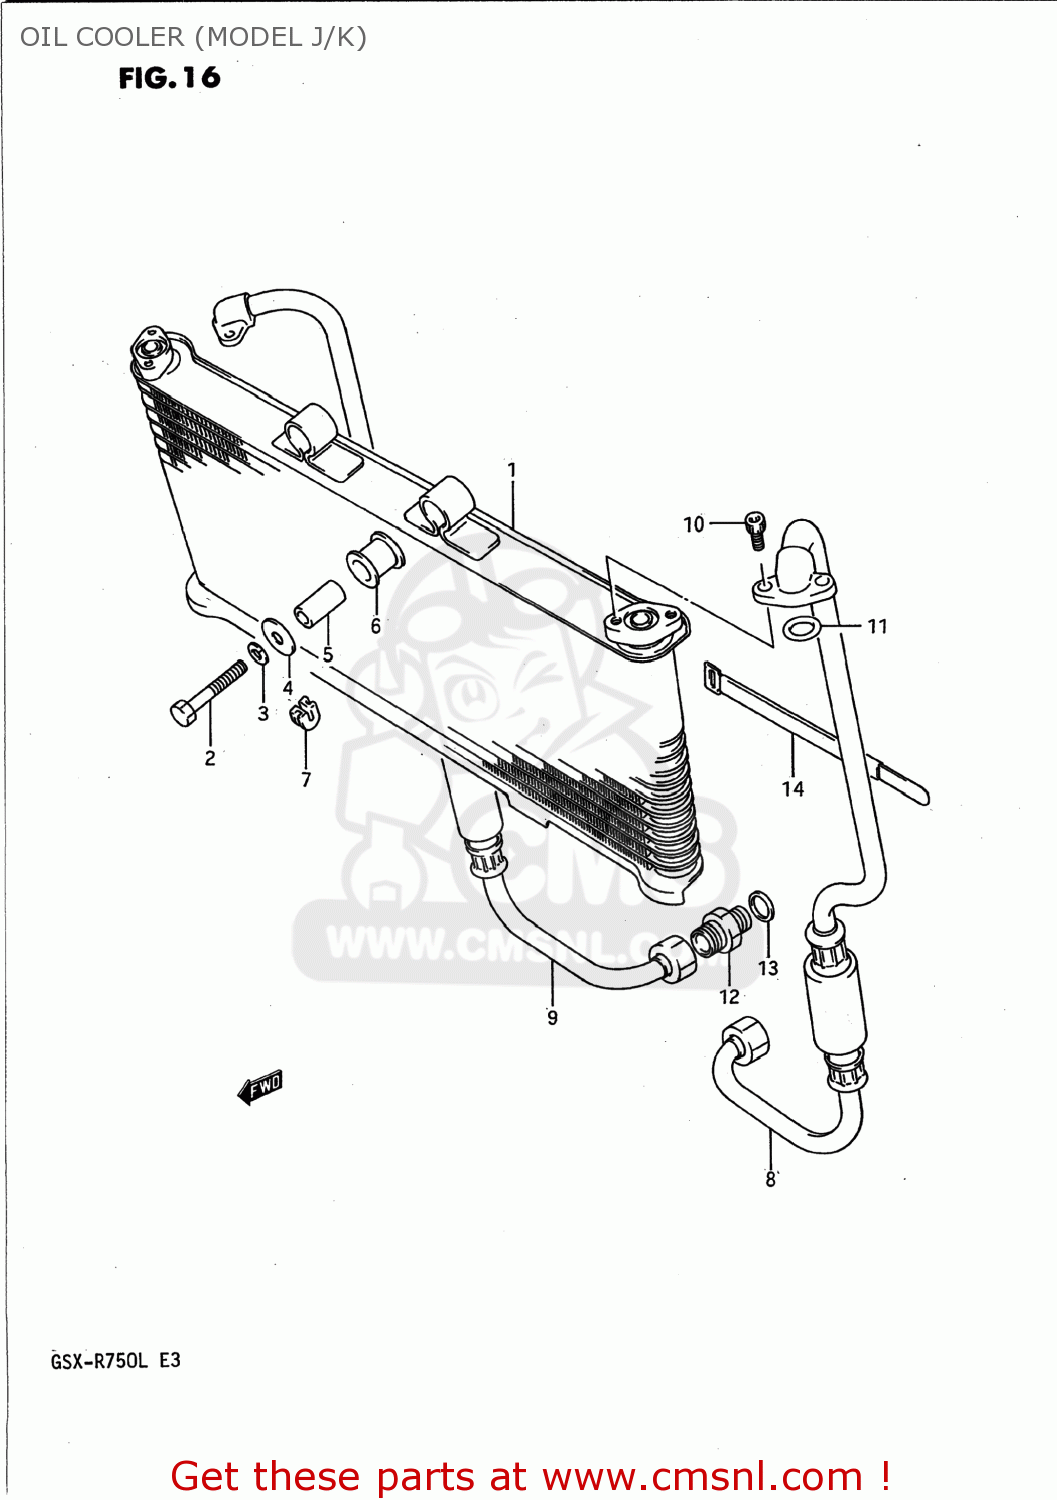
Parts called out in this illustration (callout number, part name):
1	COOLER ASSY,OIL
2	BOLT 8X40
3	WASHER,LOCK,8.
4	WASHER(8.5X23X1.2)
5	SPACER (8.8X12X24.5)
6	CUSHION,OIL COOLER NO.1
7	CUSHION,OIL COOLER NO.2
8	HOSE,OIL COOLER,L
9	HOSE,OIL COOLER,R
10	BOLT
11	O RING(D:2.4,ID:12.3)
12	BOLT UNION
13	GASKET(16X22X2) (NAS)
14	CLAMP(L:250)
